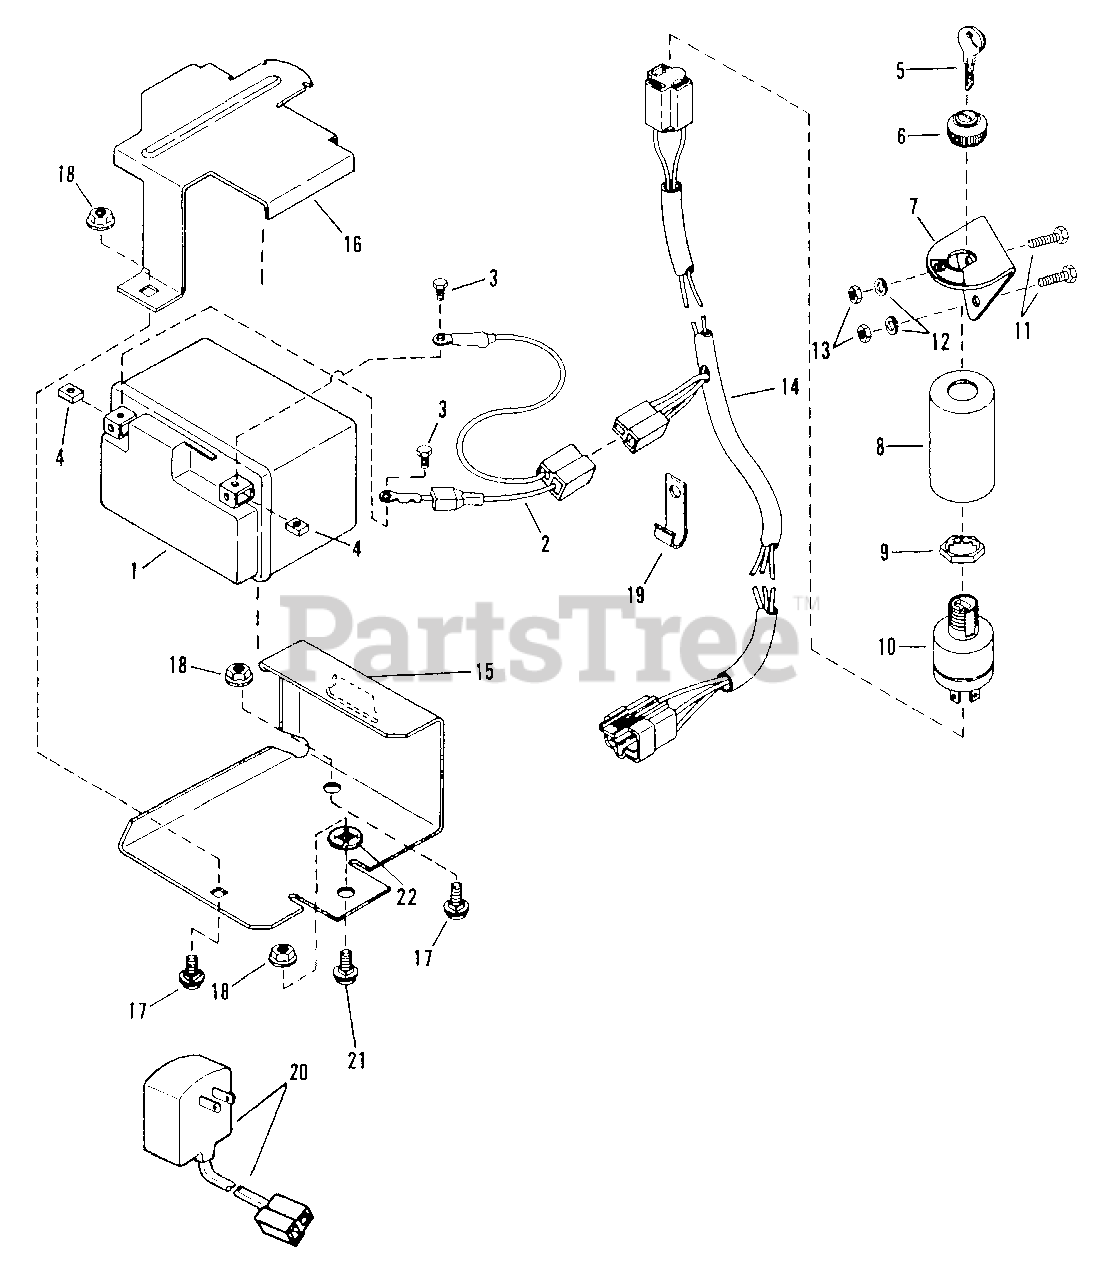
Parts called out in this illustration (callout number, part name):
1	BATTERY, 12 Volt
2	HARNESS, Battery
3	SCREW, #10-24 x 1/2" Pan Head Cross Recess
4	NUT, #10-24 Square
5	KEY
6	ASSEMBLY, Seal & Face Nut
7	BRACKET, Ignition Switch
8	COVER, Switch
9	NUT, 3/4-20 Switch
10	SWITCH, Ignition
11	SCREW, 1/4-28 x 1-3/8" Hex Hd. Cap, Gr. 5
12	WASHER, 1/4" Internal Tooth Lock
13	NUT, 1/4-28 Hex, Grade 5 or B
14	HARNESS, Wiring
15	BRACKET, Battery
16	COVER, Battery
17	BOLT, 5/16-18 x 1/2" Carriage, Grade 5
18	NUT, 5/16-18 Hex Flange Lock
19	CLIP, Wiring
20	CHARGER, Battery (60 Hertz)-P21509BE
21	BOLT, 5/16-18 x 5/8" Short Neck. Carriage, Gr. 5
22	RETAINER, 5/16" Bolt
